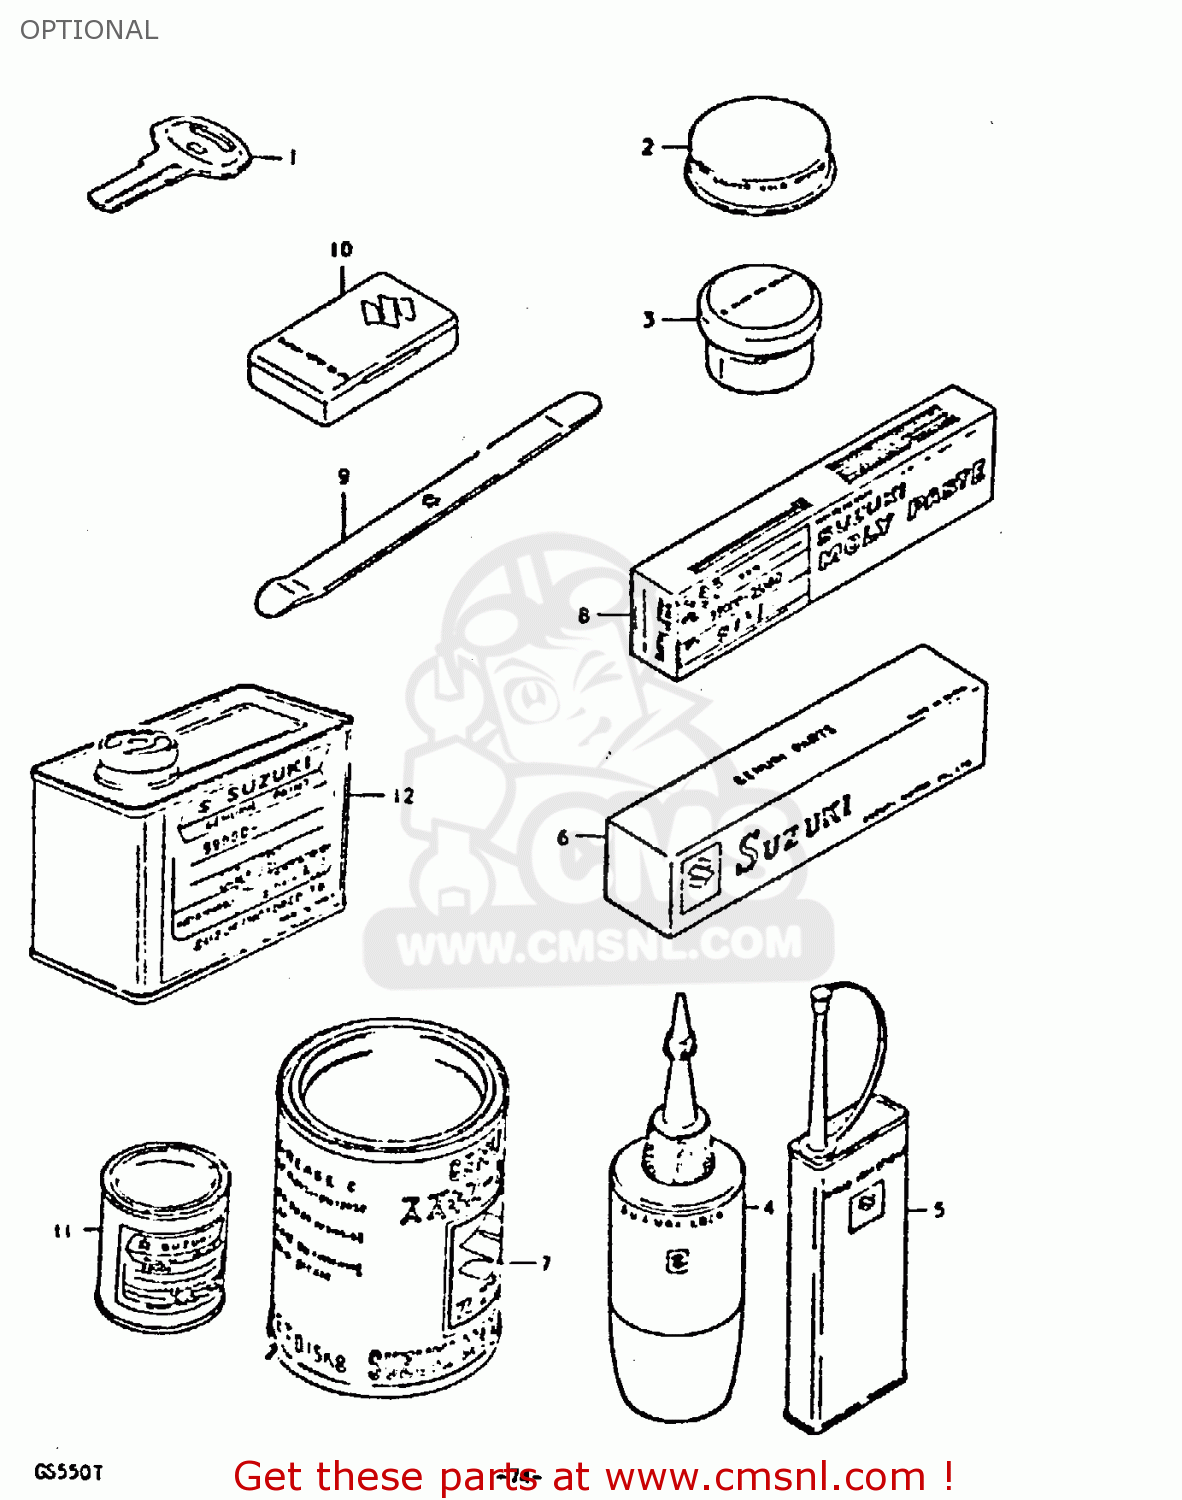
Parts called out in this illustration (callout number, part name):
1	KEY,BLANK
2	GREASE,SILICON 20G
3	GREASE,PBC FOR BRK PAD 20G
4	THREAD LOCK NO.1303B PURPL 50G
5	THREAD LOCK NO.1401 CLEAR 200G
6	BOND 1104
7	GREASE(C)EP2 LITHIUM 150G
8	SUZUKI MOLY PASTE
9	LEVER,TIRE
10	TUBE REPARING TOOL
11	PAINT,BLACK
12	PAINT (BLACK)
13	GASKET SET
